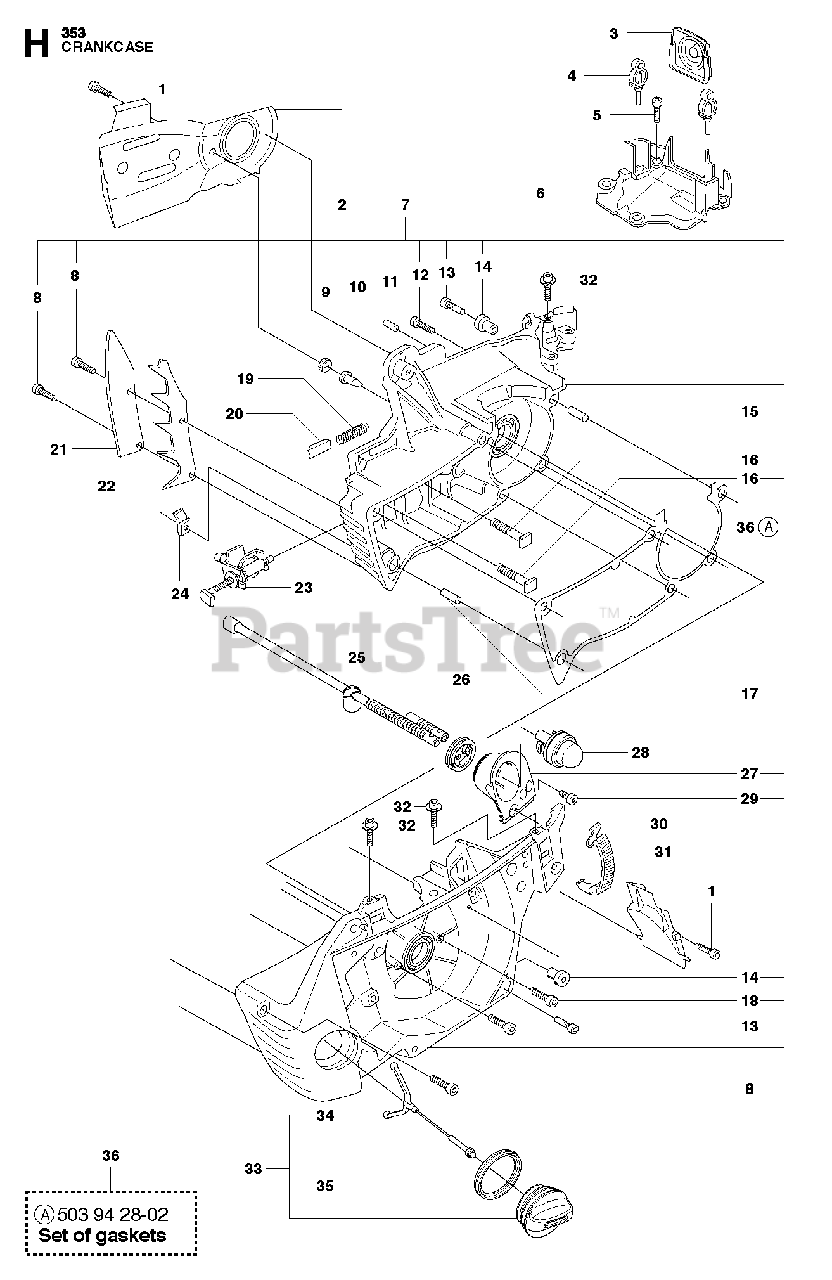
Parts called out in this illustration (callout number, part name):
2	CHAIN GUIDE PLATE
4	SUPPORT
6	CARBURETOR AREA BASE
7	CRANKCASE ASSY
8	SCREW
9	PLUG
10	VALVE-CHECK (DUCKBILL)
11	PIN
12	SCREW
13	SCREW
14	MOVEMENT LIMITER
15	SLEEVE
16	BOLT
17	SLEEVE
18	SCREW
19	LOCK SPRING
22	FELLING DOG
23	CHAIN TENSIONER
24	CHAIN CATCHER
27	BRACKET
28	AIR PURGE BUBBLE
29	SCREW IHSCT
30	BUCKLE ORANGE
33	OIL TANK CAP GREY
34	TANK LOCK
35	OILCAP GASKET
36	GASKET SET
